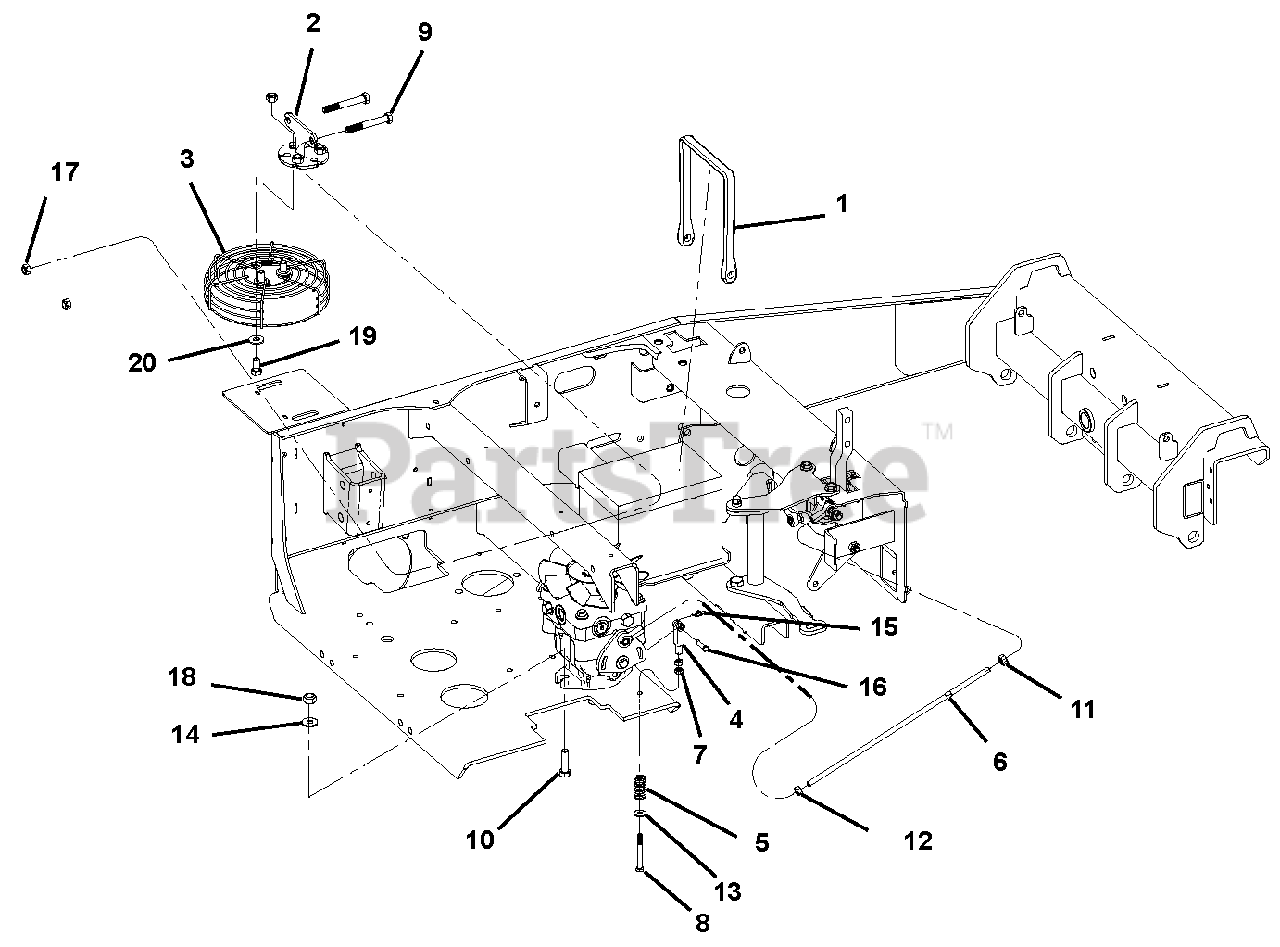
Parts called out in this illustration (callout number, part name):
1	Band, 18"
2	Weldment, Fan Shield Mounting
3	Grill, 7" Fan
4	Yoke, 1/4-20 RH Adjustable
5	Spring, Compression .784 x .092 x
6	Pump Control Rod
7	Nut, Locking, Nylon .250-20
8	Bolt, 1/4-20 x 2.75 SOC 8
9	Bolt, 3/8-16 x 2.75 Hex 5
10	Bolt, 7/16-14 x 1.50 Hex
11	Nut, 5/16-24 STD Hex
12	Nut, 5/16-24 Hex LH
13	Washer, Flat, Steel .312 x .734 x .065
14	Washer, Flat Steel .438 x 1.00 x .083
15	Ring, Rue .250 x .041 x .844
16	Pin, CVS .250 x 1.00 x .859
17	Nut, Locking, Flange .375-16
18	Nut, Locking, Crown .437-14
19	Bolt, .38-16 x .750 Hex
20	Washer, Flat, Steel .38 x .875 x .083
